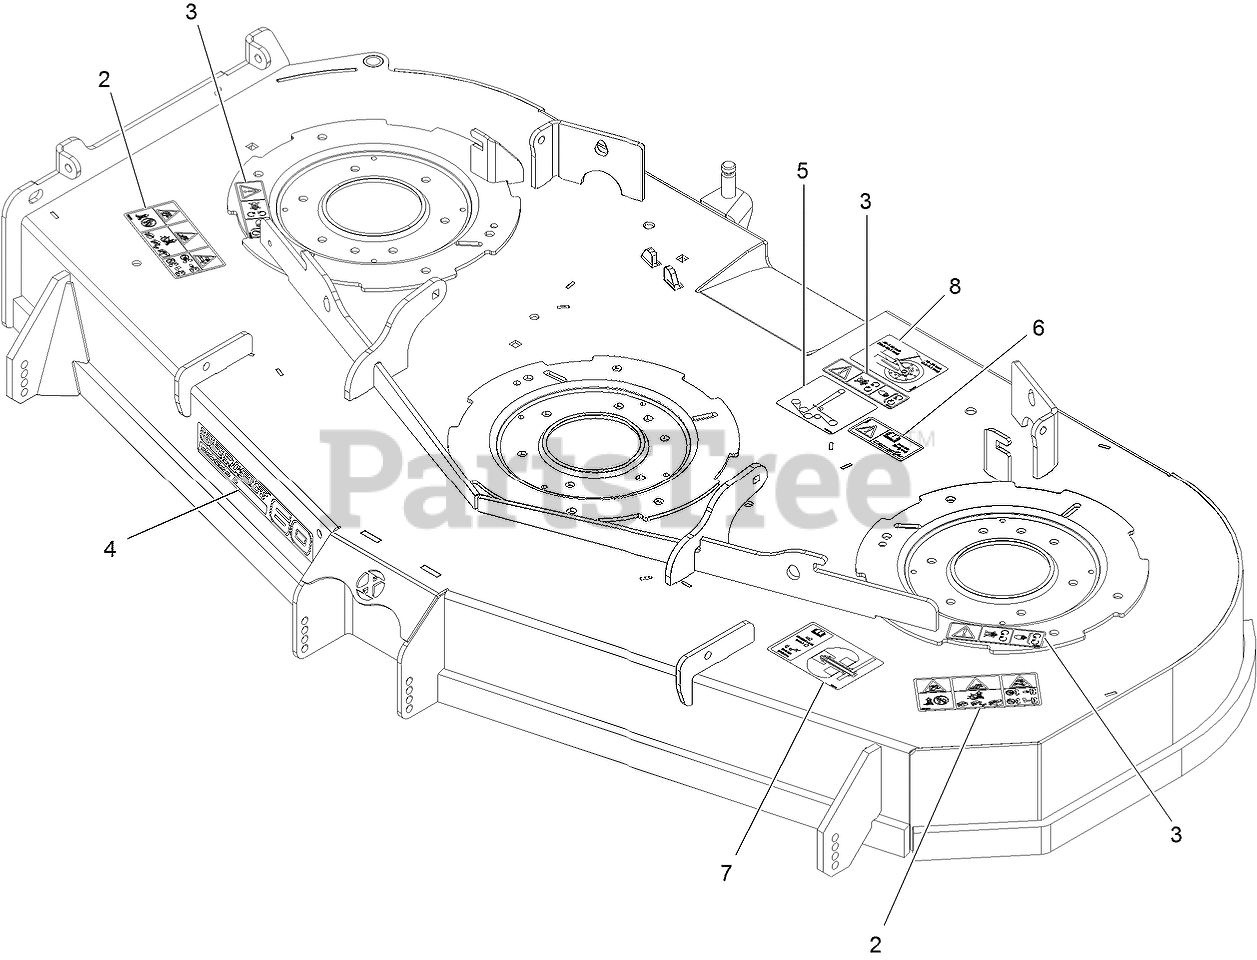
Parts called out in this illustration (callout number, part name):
2	DECAL-WARNING THROWN OBJ
3	DECAL-COVER, MISSING
4	DECAL, 604
5	DECAL-BELT ROUTING
6	DECAL-BOLT TORQUE
7	DECAL-ROLLER MOUNTING
8	Decal-Belt Guide Dist
